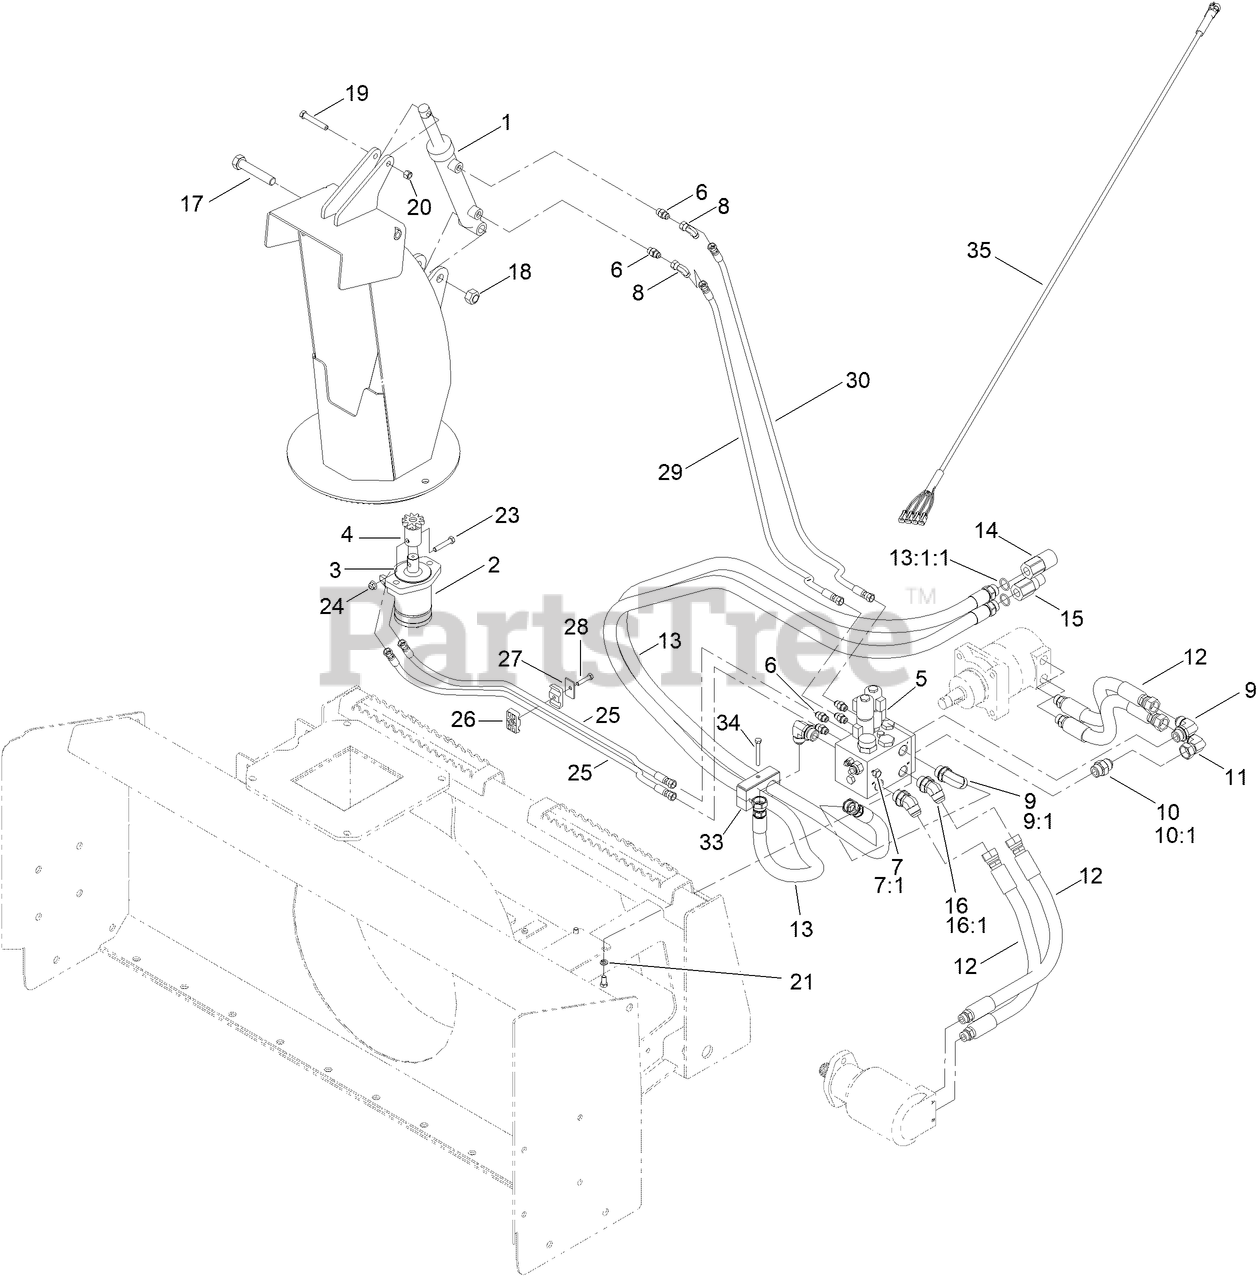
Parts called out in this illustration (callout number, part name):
1	CYLINDER-HYD
2	MOTOR-HYD, CHUTE
3	FITTING-HYD, ELBOW
4	GEAR-ROTATOR
5	MANIFOLD-SNOW BLOWER
6	FITTING,STRAIGHT,6-MORB X 6-M37JIC
7	PLUG-HH
7:1	O-RING
8	ELBOW-SWIVEL, 90 DEG
9	FITTING-ELBOW, 90 DEG
9:1	O-RING
10	FITTING-STRAIGHT
10:1	O-RING
11	FITTING-ELBOW, 90
12	HOSE-HYD ASM
13	HYD HOSE ASM
13:1	FITTING-STRAIGHT
13:1:1	O-RING
14	FITTING-HYD
15	FITTING-HYD
16	FITTING-JIC 37
16:1	O-RING
17	SCREW-HH
18	NUT-LOCK
19	SCREW-HH
20	NUT-LOCK, NI
21	WASHER-LOCK
23	SCREW-HH
24	NUT-HF, NI
25	HOSE-HYD
26	CLAMP-TUBE
27	COVERPLATE
28	SCREW-HH
29	HOSE-HYD
30	HOSE-HYD
33	CLAMP-HOSE
34	SCREW-HH
35	HARNESS-WIRE
